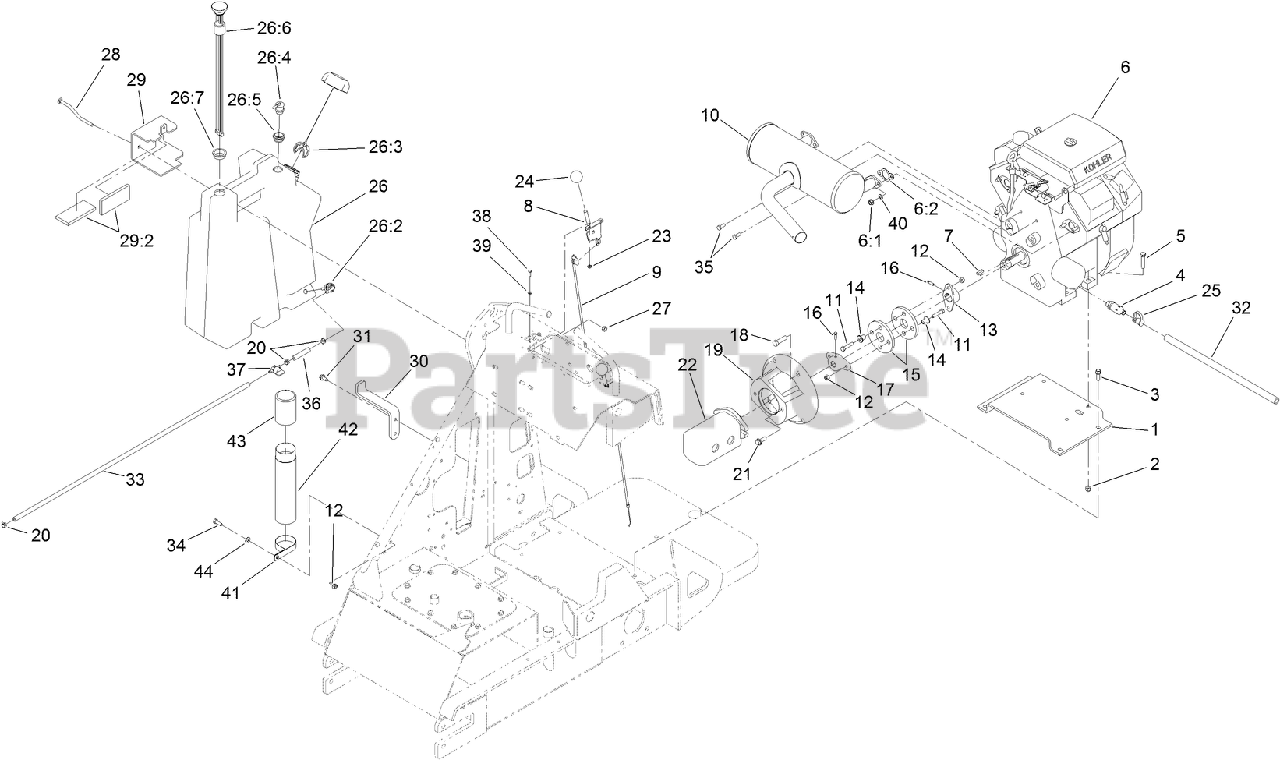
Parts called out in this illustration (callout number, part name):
1	MOUNT-ENGINE
2	NUT-LOCK, NI
3	SCREW-TAPTITE
4	VALVE-DRAIN, OIL
5	SCREW-HH
6	ENGINE-KOHLER, CH20S
6:1	NUT-HF
6:2	GASKET-EXHAUST
7	KEY-SQUARE
8	LEVER-CONTROL
9	CABLE-CONTROL
10	Muffler
11	SCREW-HH
12	NUT-LOCK, NI
13	HUB-ENGINE
14	SPACER
15	COUPLING-RUBBER
16	SCREW-SQH
17	HUB-PUMP
18	SCREW-HH
19	MOUNT-PUMP
20	CLAMP-HOSE
21	SCREW-HHF
22	HYD PUMP ASM
23	NUT-KEPS
25	CAP-DUST
26	RH FUEL TANK ASM
26:2	FITTING-FUEL, BULKHEAD
26:3	CAP-FUEL
26:4	VALVE-ROLLOVER
26:5	GROMMET
26:6	GAUGE-LEVEL, FUEL
26:7	GROMMET
27	NUT-HEX, SIDE DEFORM
28	BOLT-MOUNT
29	RH TANK MOUNT ASM
29:2	PAD-FOAM
30	MOUNT-TANK, BOTTOM
31	SCREW-HWHTF
33	HOSE-FUEL
34	SCREW-HH
35	SCREW-HH
36	HOSE-FUEL
37	VALVE-FUEL
39	WASHER-FLAT
40	WASHER-LOCK
41	CLAMP-R
42	TUBE-MANUAL
43	CAP-HOUSING
44	WASHER-PLAIN
